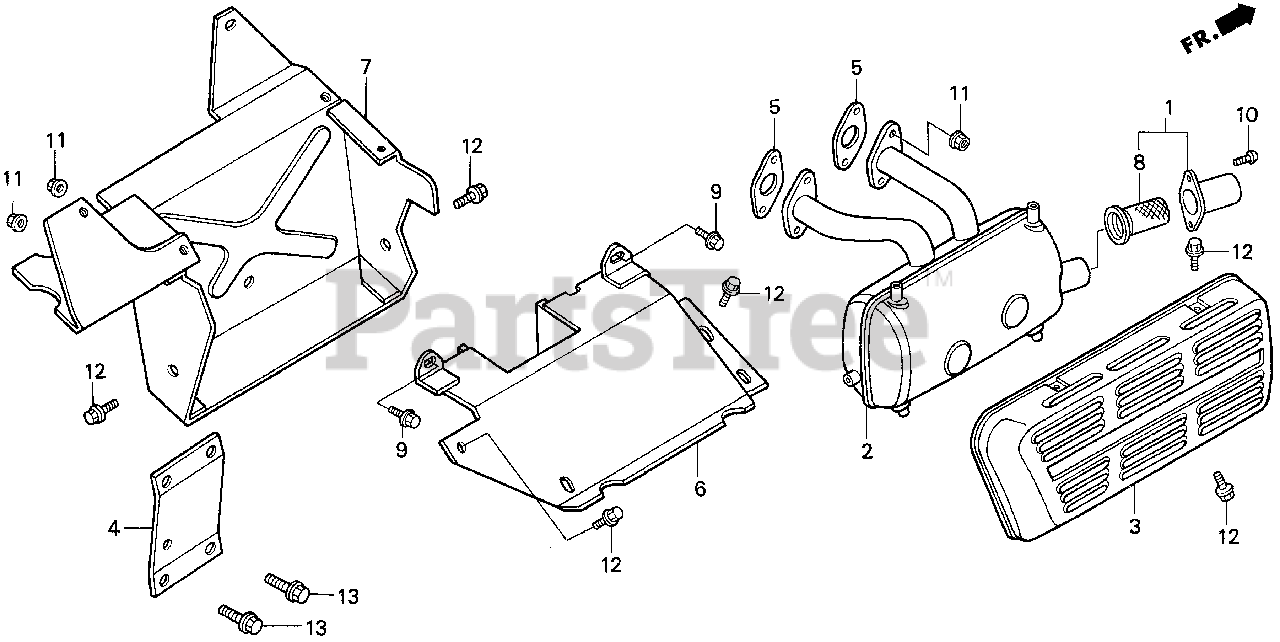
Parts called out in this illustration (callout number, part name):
1	CAP SET, ARRESTER
2	MUFFLER
2	MUFFLER (ARRESTER)
3	PROTECTOR, MUFFLER
4	BRACKET, MUFFLER
5	GASKET, EX. PIPE
6	PROTECTOR, HEAT (UPPER)
7	PROTECTOR, HEAT (LOWER)
8	ARRESTER, SPARK
9	BOLT, FLANGE (6X12) (CT200)
10	SCREW, PAN (5X8)
11	NUT, FLANGE (8MM)
12	BOLT, FLANGE (6X10)
13	BOLT, FLANGE (8X16)
